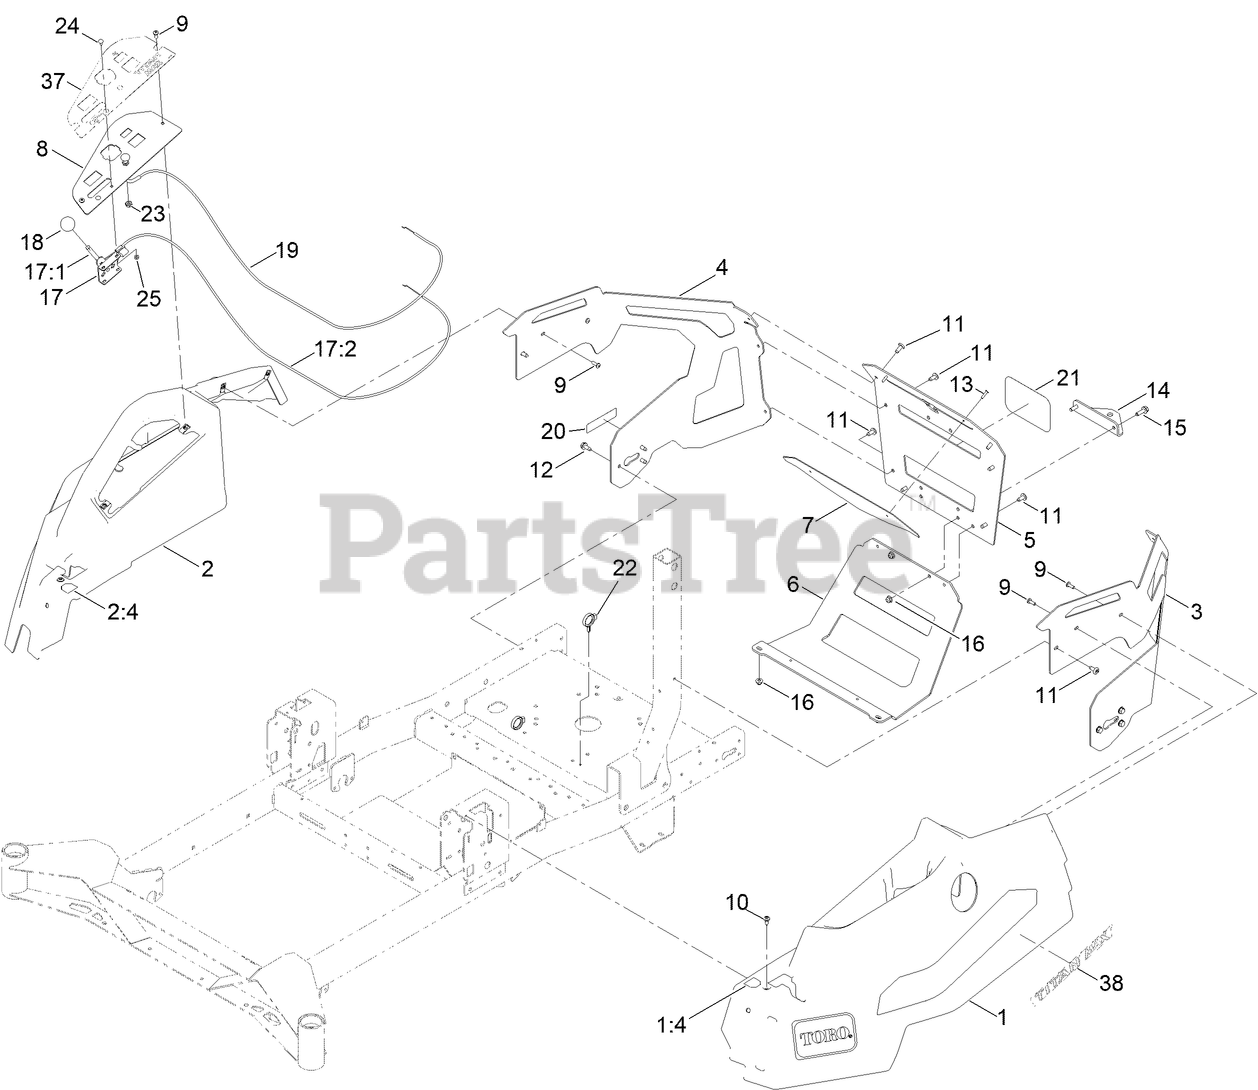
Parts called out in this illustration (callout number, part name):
1	TITAN MAX LH POD ASM
1:4	DECAL-CONTROL LEVER, LH
2	TITAN MAX RH POD ASM
2:4	DECAL-CONTROL LEVER, RH
3	GUARD-ENGINE, LH
4	GUARD-ENGINE, RH
5	GUARD-ENGINE
6	GUARD-MUFFLER
7	PLATE-BACKER
8	PANEL-CONTROL
9	SCREW-PH
10	SCREW-SHOULDER
12	SCREW-HWHTF
13	RIVET-TRIFOLD
14	BRACKET-HITCH
15	SCREW-HHF
16	NUT-HF
17	THROTTLE CONTROL ASM
17:1	LEVER-THROTTLE
18	KNOB-BALL
19	CABLE-CHOKE CONTROL
20	DECAL-SPARK ARRESTER
21	DECAL
22	CLAMP-HOSE
23	NUT-HJ
24	BOLT-CARR
25	NUT-LOCK, NI
37	DECAL-PANEL, CONTROL
38	DECAL-TITAN MAX
